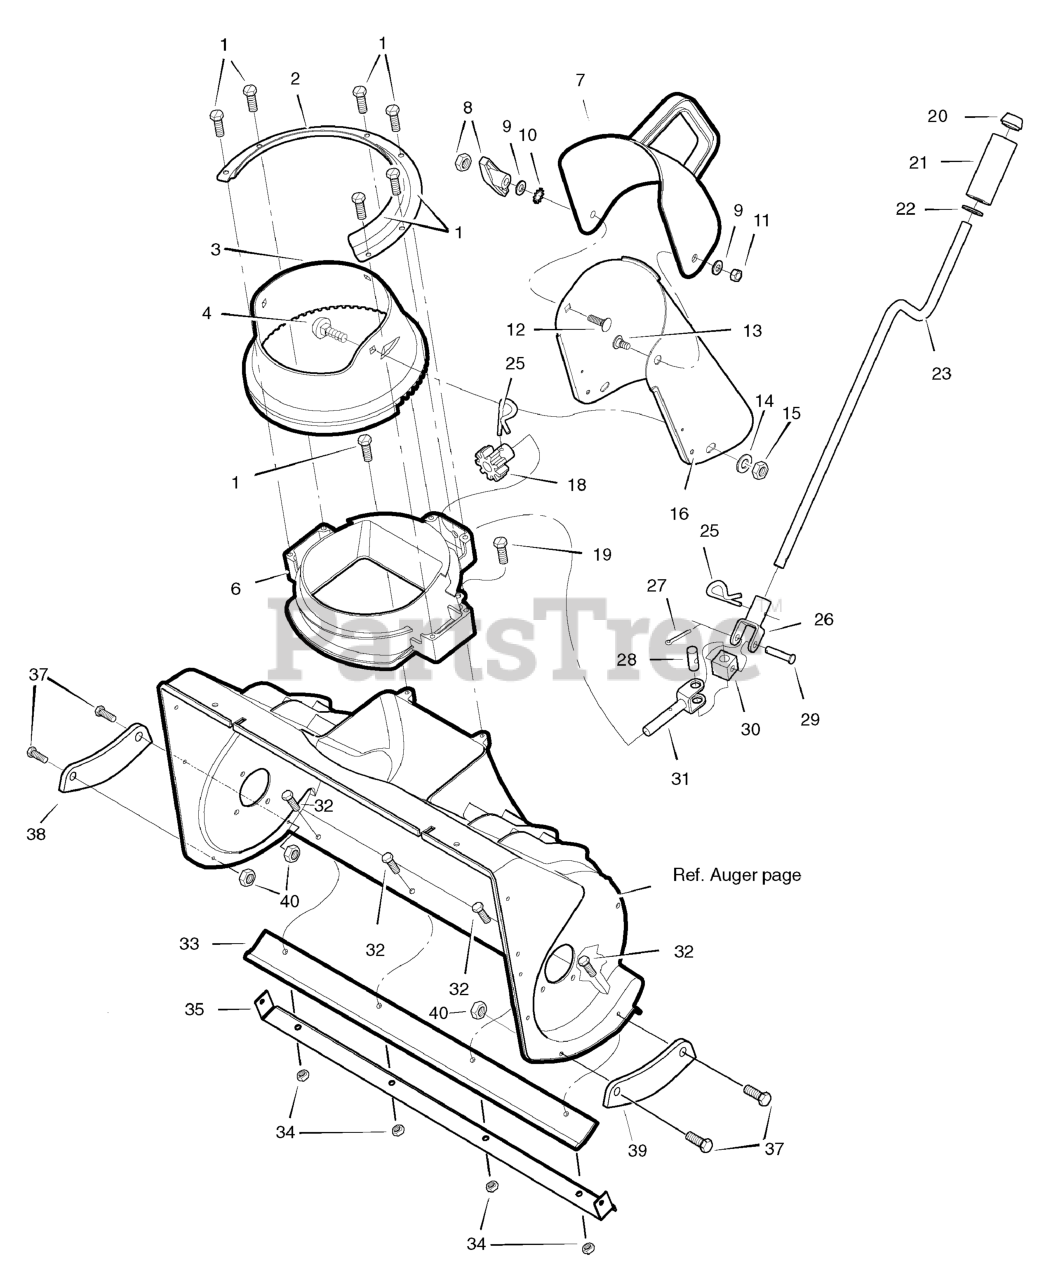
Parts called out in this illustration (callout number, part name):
1	SCREW, 1/4 - 14
2	RETAINER, Chute Ring
3	RING, Chute
4	BOLT, Carriage, 5/16 - 18 x 3/4
6	NECK, Chute
7	CHUTE, 22" Upper
9	WASHER
10	LOCKWASHER, Shakeproof
11	LOCKNUT, Hex, 5/16 - 18
12	BOLT, Carriage, 5/16 - 18
13	BOLT, Upper Chute
14	WASHER, Flat, 13/32
15	NUT
16	CHUTE, Lower
18	GEAR, 9-Tooth
19	SCREW, 1/4 - 14 x 3/4
20	NUT, Push
21	KNOB, Sleeve
22	WASHER, Flat, 13/32
23	CRANK, Chute Rotation
25	PIN, Hair
26	YOKE ASSEMBLY, Adapter
27	PIN, Cotter, .5
28	PIN, Universal Joint
29	PIN, Clevis
30	HOUSING, Universal
31	ROD, Lower Crank
32	SCREW, 1/4 - 20 x 3/4
33	BLADE, Scraper
34	LOCKNUT, Hex, 1/4 - 20
35	PLATE, Reinforcement
37	SCREW, 10-32 x 1
38	SKID SHOE, RH
39	SKID SHOE, LH
40	NUT, Nylock, 10-32
